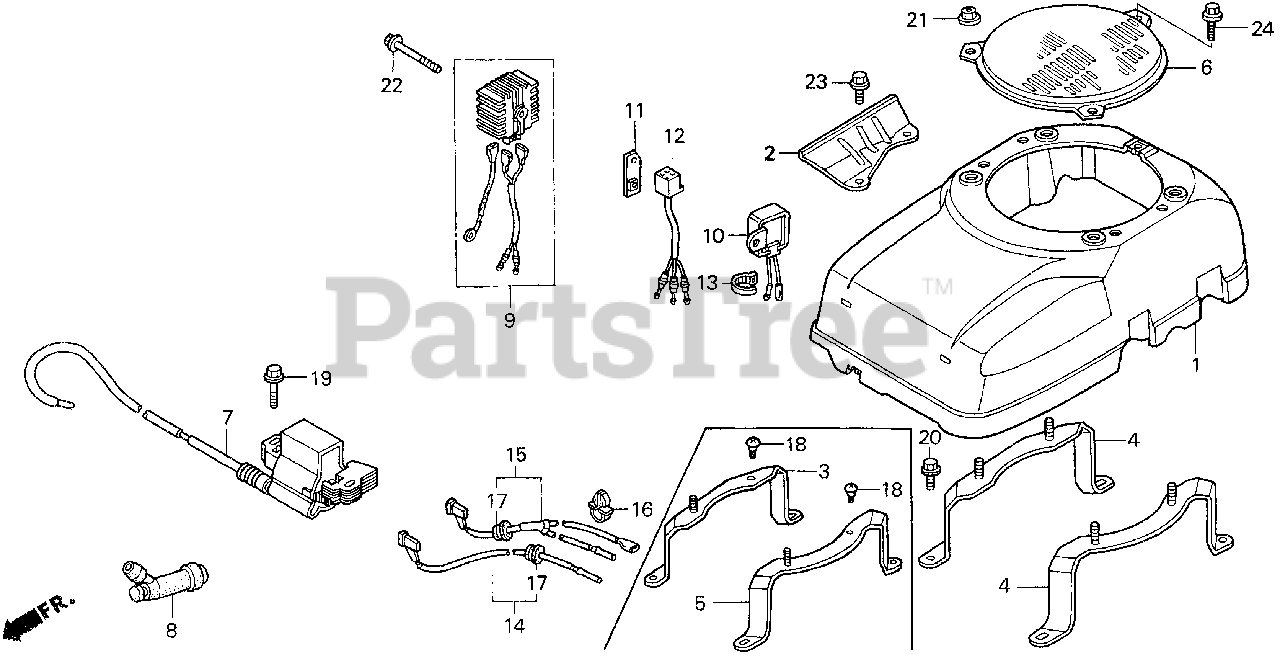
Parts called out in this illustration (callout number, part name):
1	COVER COMP., FAN *R8* (BRIGHT RED)
1	COVER COMP., FAN *NH1* (BLACK)
3	BRACKET, R. FAN COVER
5	BRACKET, L. FAN COVER
6	COVER, SCREEN *NH1* (BLACK)
6	COVER, SCREEN *R8* (BRIGHT RED)
7	COIL ASSY., IGNITION
8	CAP ASSY., NOISE SUPPRESSOR
9	RECTIFIER ASSY., SILICON
11	BRACKET, RECTIFIER
12	SUB-WIRE HARNESS ASSY. (AYP)
13	BAND B1, CABLE
14	WIRE, STOP SWITCH (AYP)
17	GROMMET, WIRE
18	SCREW, SPECIAL (6X8)
19	BOLT, FLANGE (6X28)
20	BOLT, FLANGE (6X16)
21	NUT, FLANGE (6MM)
22	BOLT, FLANGE (6X32)
24	BOLT, FLANGE (6X10)
